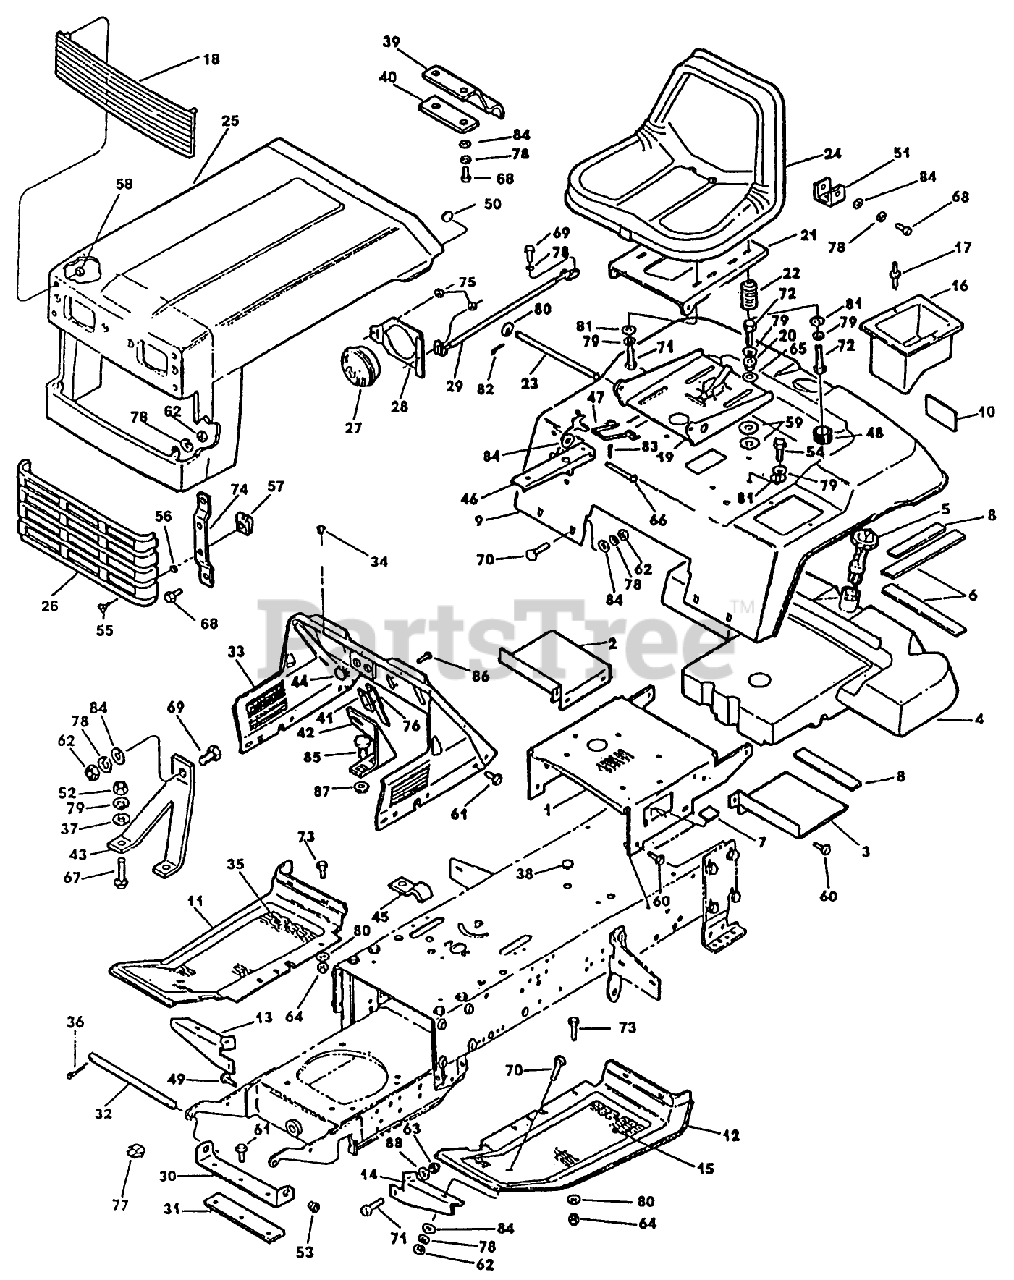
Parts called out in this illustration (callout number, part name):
4	TANK - FUEL
5	GUAGE ASSEMBLY-FUE
8	PAD - FUEL TANK
10	REFLECTOR
17	Rivet
19	SEAT SUPPORT AY
21	PIVOT AY - SEAT *B
23	PIN
24	SEAT
25	HOOD&GRILLE (UPS) *G
26	INSERT - GRILLE
32	ROD - HOOD PIVOT
33	INST.PANEL & DECAL *B
43	BRACKET-SUPPORT
46	LATCH - SEAT PAN *B
48	CAP-PROTECTOR
52	NUT SS
53	BEARING-NYLINER
55	FASTENER-1/4 TURN
59	WASHER-PLASTIC
62	NUT
63	NUT
64	NUT-LOCKING
66	PIN
67	BOLT - CARRIAGE
68	SCREW-HH
69	SCREW
71	SCREW - HEX
72	SCREW
77	CLIP-RETAINER, WIRE
80	WASHER
88	WASHER
